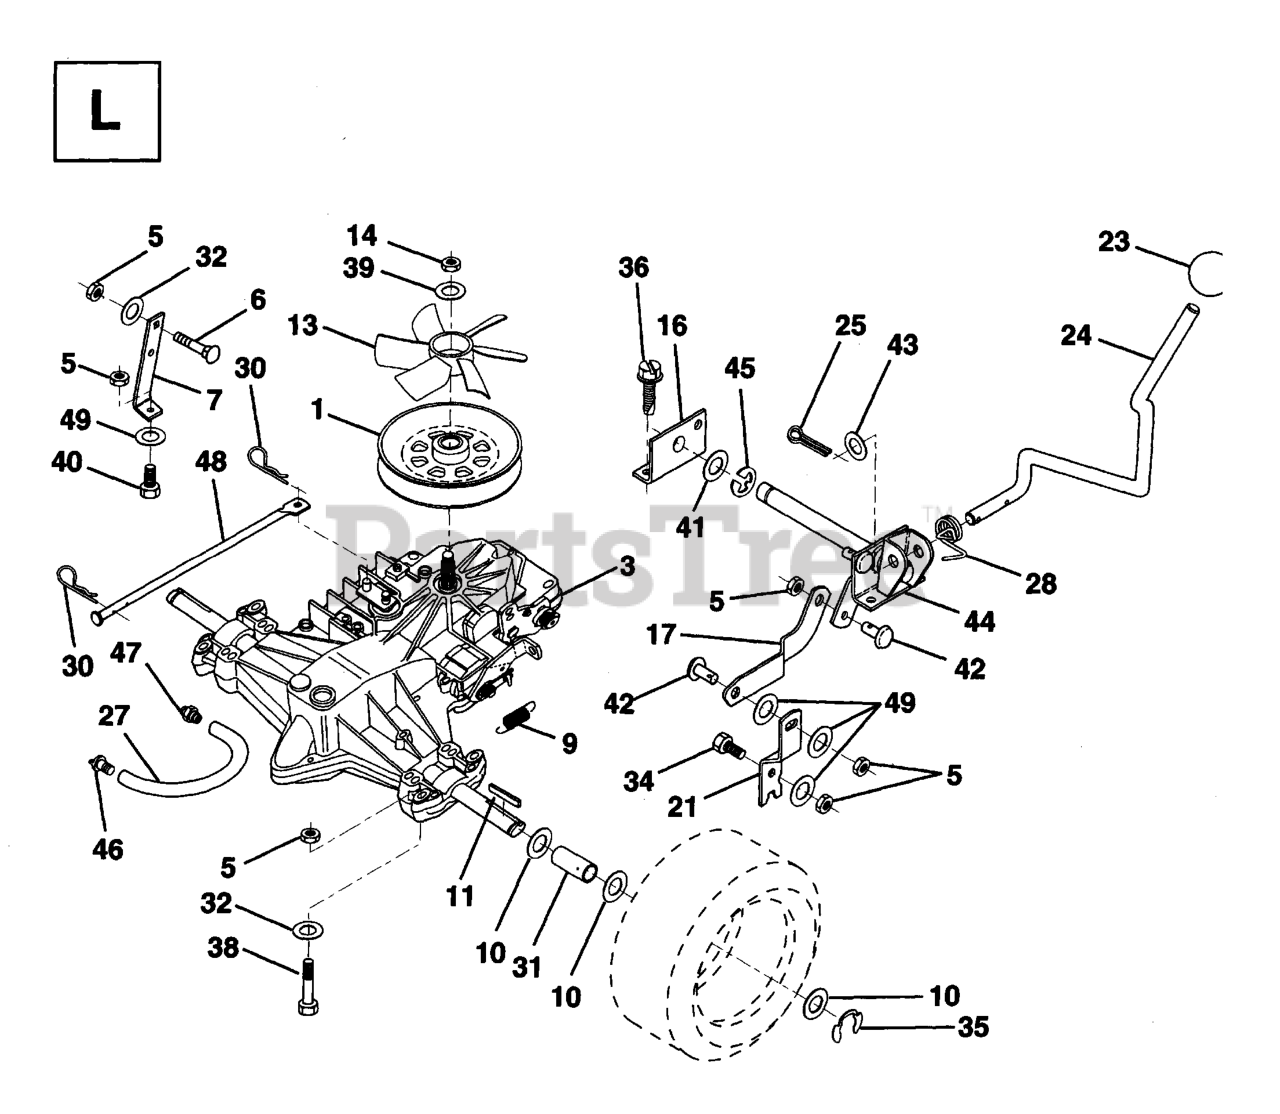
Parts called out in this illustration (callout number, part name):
1	PULLEY.V-GROOVE
3	TRANSAXLE.HYDRO.319-0500.LR
5	NUT.71038.31-18.HEX.NYLOCK
6	RP BOLT 5/16-18 X3/4 ZN/YEL GR
9	SPRING T
11	SQUARE KEY
13	FAN.TRANSMISSION.HYDRO.6"
16	SUPPORT, SHIFT HANDLE
17	LINK, SHIFT
21	LEVER, SHIFT
23	KNOB.DUCKHEAD.1/2
24	ROD, SHIFTER
25	PIN COTTER
27	LINE FUEL HYD 4"
28	SPRING, TORSION
30	RETAINER M
31	SPACER SPLIT
32	WASHER
34	BOLT RB
36	SCREW
38	Bolt, Hex, Fin. 5/16 x 18 UNC x 2-1/2
40	BOLT
41	Washer 21/32 x 1-1/4 x 13 Ga.
43	WASHER
44	SHAFT PIVOT ASMBLY
45	RETAINING RING LT
46	CAP, VENT ASSY
47	O-RING KIT 70110
49	WASHER M
